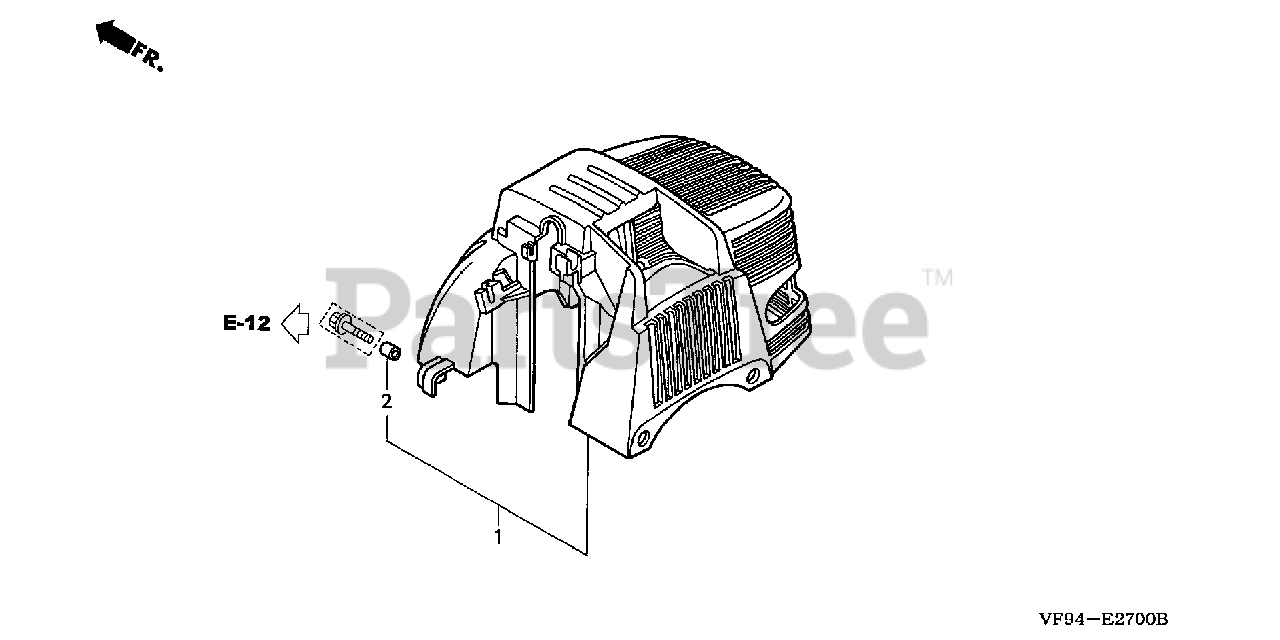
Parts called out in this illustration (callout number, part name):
1	COVER, TOP *R8* (BRIGHT RED)
1	COVER, TOP *R280* (POWER RED)
2	COLLAR, TOP COVER
